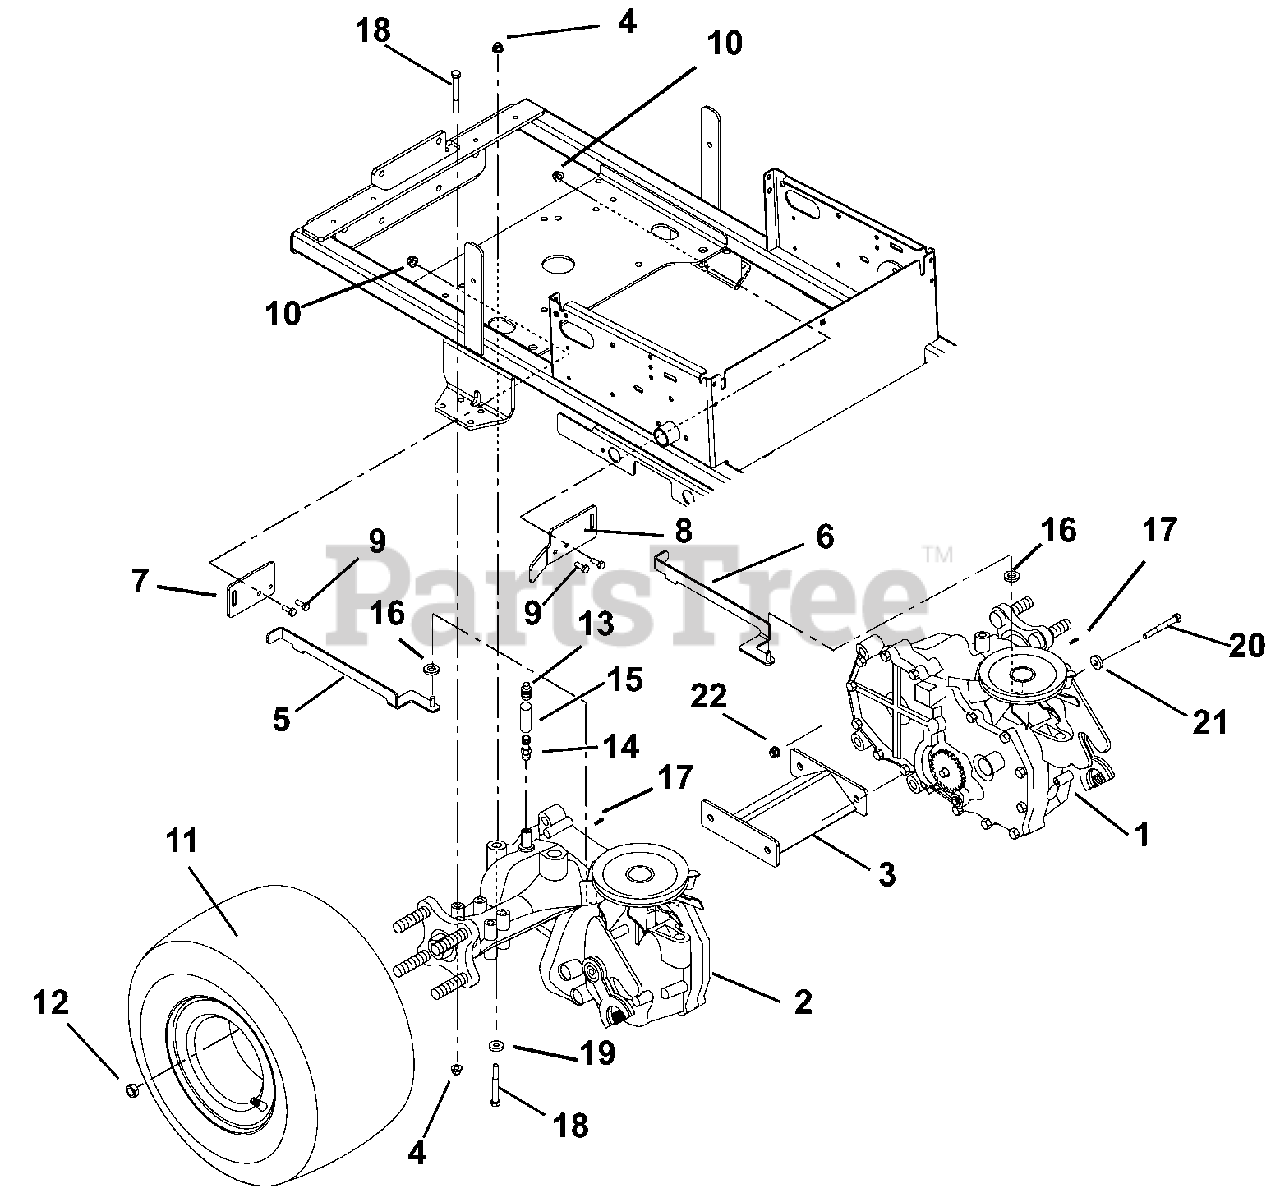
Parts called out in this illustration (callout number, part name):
1	EZT, Left Hand Transaxle-Hydrogear (For service please contact Hydro-Gear) (094, 096, 098)
2	EZT, Right Hand Transaxle-Hydrogear (For service please contact Hydro-Gear) (094, 096, 098)
3	Weldment, Transaxle Support
4	Nut 5/16-18 Flange Nyloc
5	Weldment, Dump Valve (RH)
6	Weldment, Dump Valve (LH)
7	Bracket, Dump Valve
8	Bracket, Dump Valve/Clutch Stop (094, 096)
9	Bolt-Hex .25-20 x .75 Grade 5
10	Nut, Locking Nylon .250-20
11	Assembly, Tire 18 x 8.5-8 (094, 096)
12	Nut, Lug .50-20
13	Cap, Vent .50
14	Fitting, Straight .50
15	Hose, Vent
16	Washer-Flat-Steel .265 x .50 x .087
17	Pin-Hair-Internal .06 x .18 x .77
18	Bolt, Hex .31-18 x 2.75
19	Washer, Flat Steel .328 x .87 x .179
20	Bolt, Hex .38-16 x 2.50 Grade 5
21	Washer, Flat Steel .406 x 1.00 x .188
22	Nut, .38-16 Nyloc Flange
